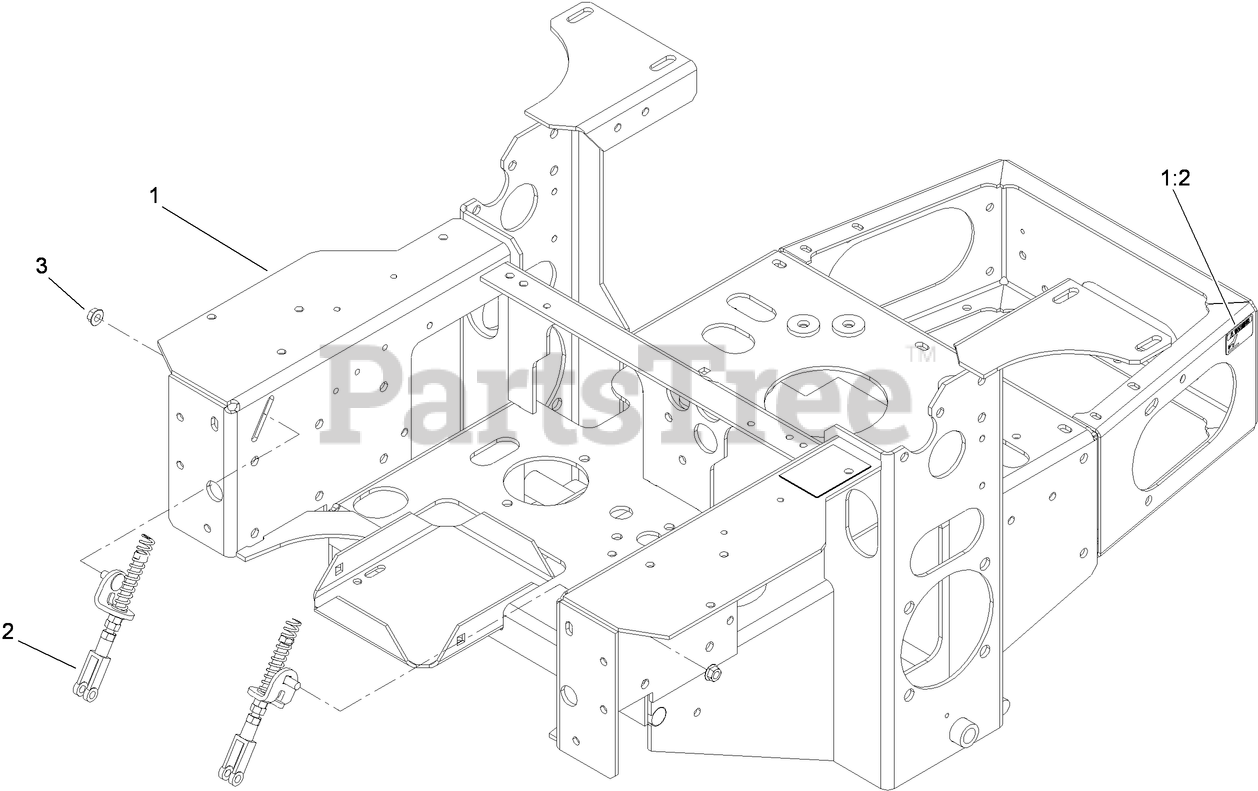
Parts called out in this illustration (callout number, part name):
1	MAIN FRAME ASM
1:2	DECAL-SURFACE, HOT
2	NEUTRAL RETURN ASM
3	NUT-HF
